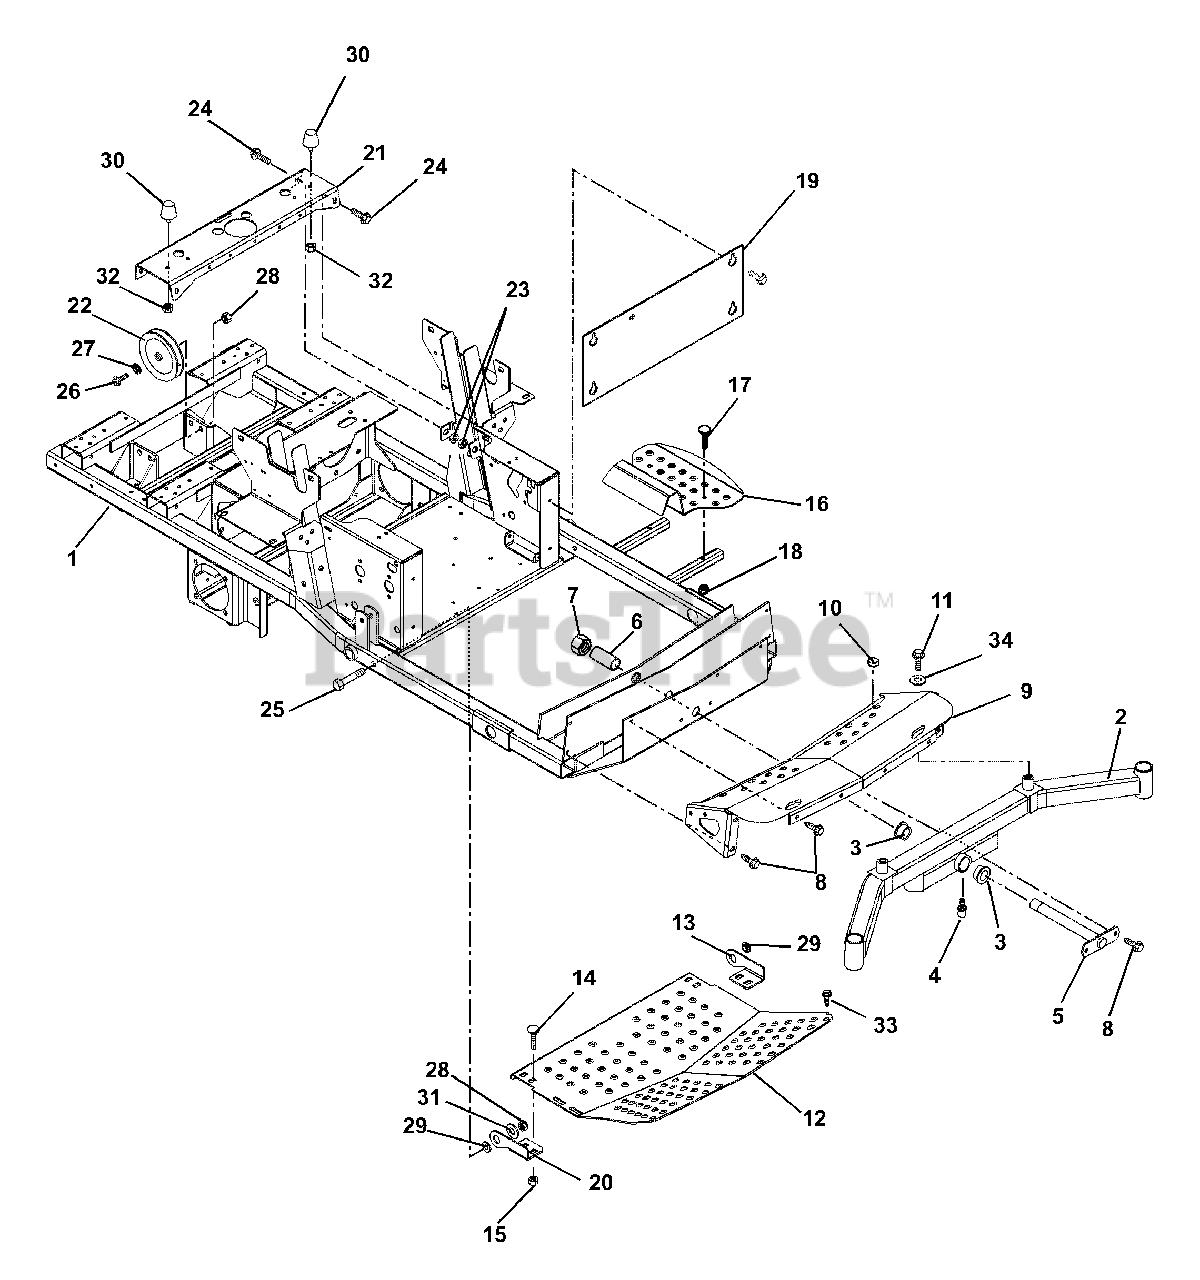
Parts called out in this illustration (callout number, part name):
1	WMT, LIQUID COOLED FRAME - BLK
2	WMT, FRONT AXLE
3	BSHG-FLG1.020X1.385X.75X1.75NY
4	FTG-LUBE .25-28X.256 YWZC
5	PIN - AXLE
6	SPACER 1.009 X 1.250 X 4.23
7	NUT-LK-NYL 1.0-14 YWZC
8	@SCR-TAP .38-16X.75 HWH TR YWZ
9	WMT, AXLE COVER
10	BUTTON BUMPER
11	BLT-HEX .50-20X1.00 GR5 YWZC
12	PANEL - INSPECTION (RED)
13	HINGE, FOOTBOARD LH
14	@BLT-RDHDSQNK .38-16X1.00 G5YZ
15	@NUT-LK-TOP-FLG .38-16 YWZC
16	STEP, INGRESS (BLACK)
17	@BLT-RDHDSQNK .31-18X1.75 G5YZ
18	@NUT-LK-TOP-FLG .31-18 YWZC
19	PLATE - KICK (RED)
20	HINGE, FOOTBOARD RH
21	CHANNEL, CROSS (BLACK)
22	PLY-V 6.0 X .500 ID DBL BRG.
23	NUT-RTNR .375-16X.37
24	BLT-SERHFWH .375-16X1.0 YWZC
25	@BLT-HEX .50-13X3.25 GR5 YWZC
26	@BLT-HEX .50-13X2.25 GR5 YWZC
27	WSHR-FL-STL .505X.880X.072 YWZ
28	@NUT-LK-TOP-FLG .50-13 YWZC
29	BSHG-FLG .515X.750X.285X1.120
30	BUMPER, RUBBER CONE,STUD MOUNT
31	@WSHR-FL-STL.563X1.38X.109YWZC
32	@NUT-SPNLK-FLG .312-24 YWZC
33	@SCR-TAP .38-16X1.00 HWH TR YZ
34	WSHR-FL-STL .518X2.0X.105 YWZC
